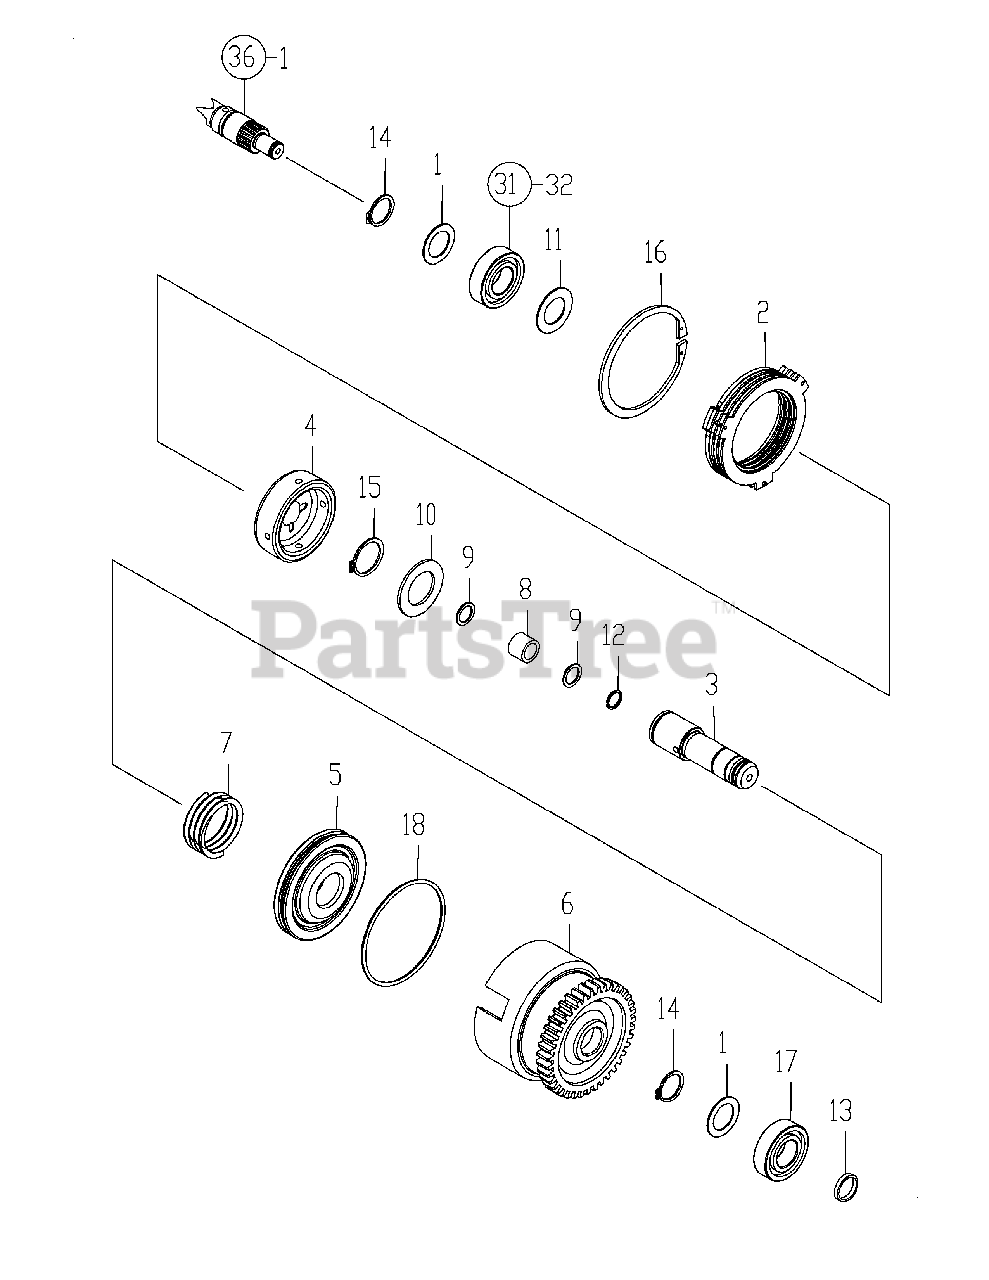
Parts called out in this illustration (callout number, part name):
2	DISC KIT, FRICTION
4	COLLAR, SPLINE
6	GEAR, CLUTCH Z=39
7	SPRING, PTO RETURN
8	NEEDLE, 121718
9	WASHER, 13X17X1
10	WASHER, 25X42X2
11	WASHER, 20X34X1
13	RING, SEAL 17203
18	PACKING, G 75.0
